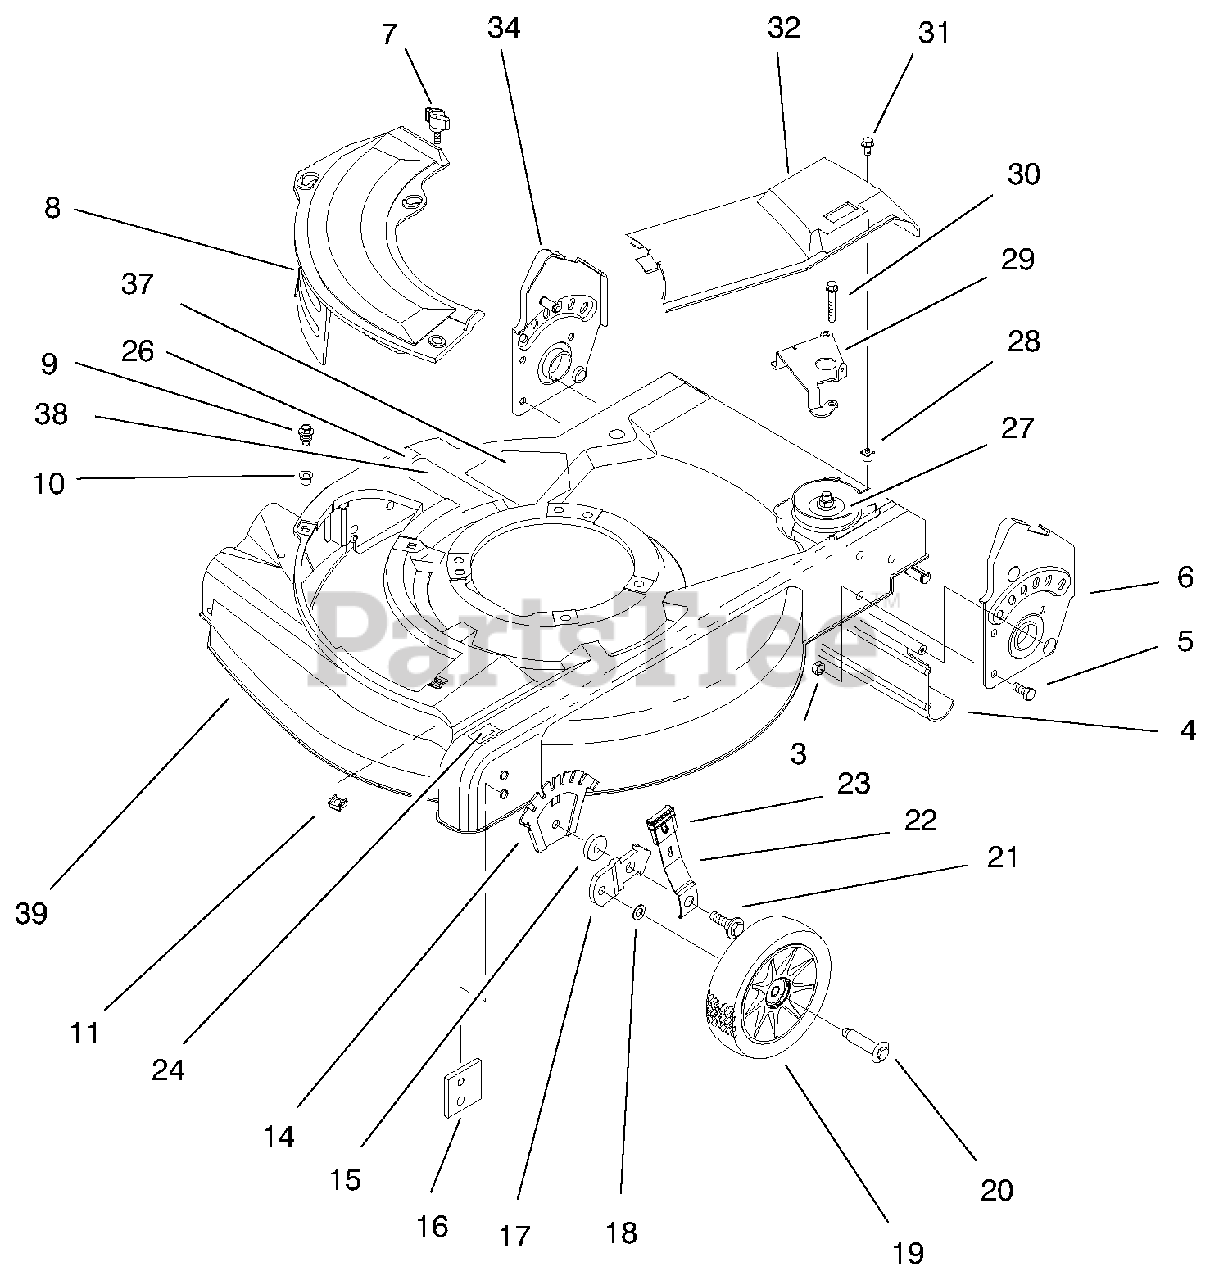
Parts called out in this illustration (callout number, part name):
3	Nut-Lock
4	Shield-Trailing
5	Screw-HH
6	ASM-Handle Bracket
7	Knob-Cover Plate
8	Mulch Plate-21"
9	Screw-Sems
10	Grommet-Plastic
11	Nut-Cage
14	Plate-Height Adjust
16	Plate-Baffle
17	Bracket-Wheel Height Adj
19	ASM-Wheel & Tire 6"
20	Bolt-Shoulder
21	Bolt-Shoulder
22	Spring Arm-Front
23	Knob-Height Adjust
24	Decal-HOC
26	Decal-HOC
27	ASM-Gear Case
28	Grommet
29	Guide-Transmission
30	Screw-Thread Forming
31	Screw-Phil
32	Cover-Drive
34	ASM-Handle Bracket
37	Decal-Danger
38	Decal-Discharge
39	ASM-Housing & Baffle
